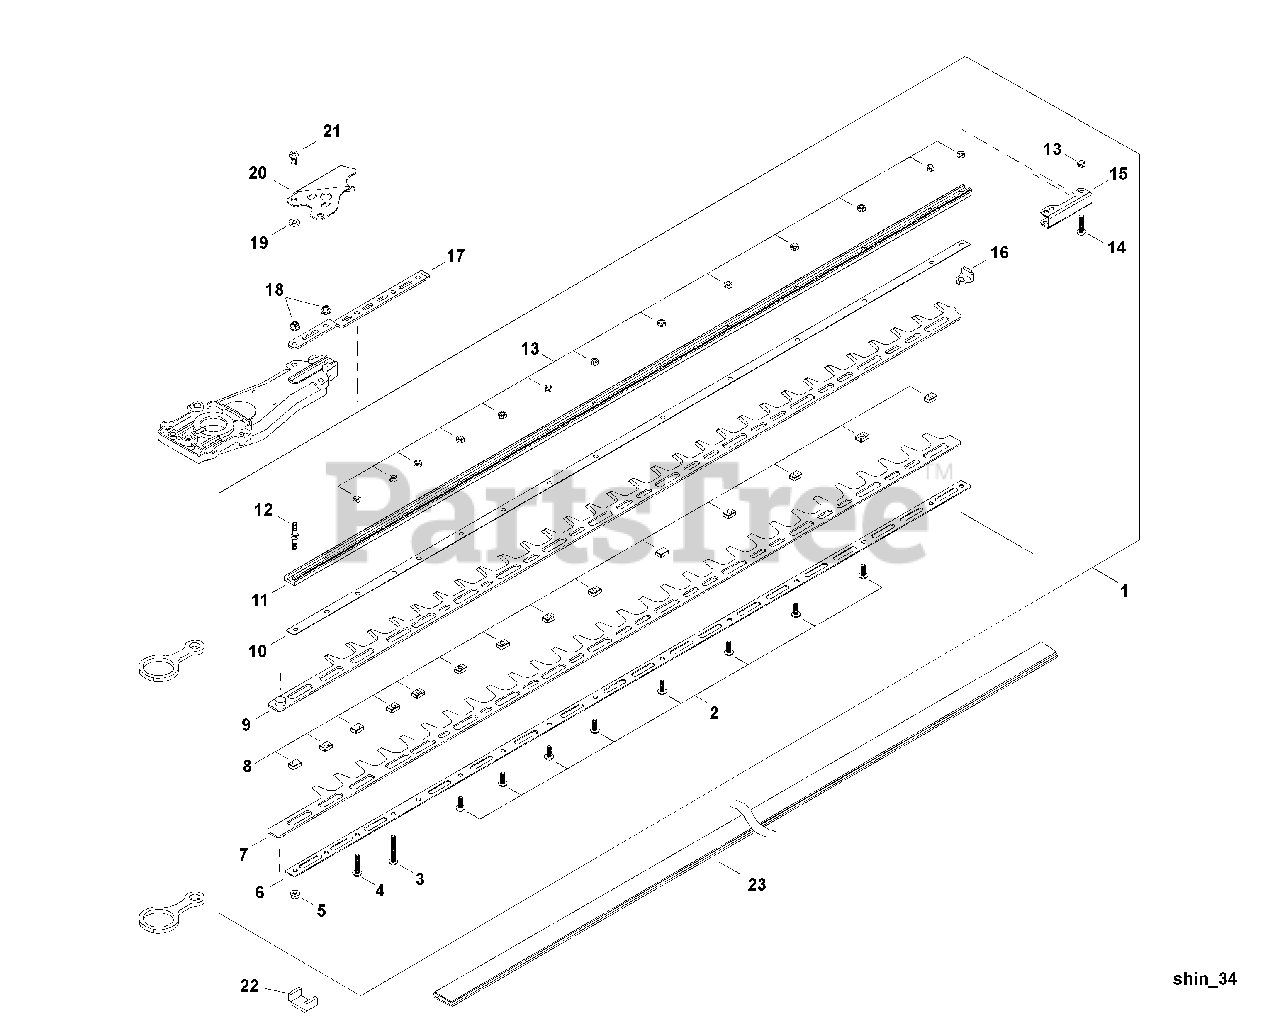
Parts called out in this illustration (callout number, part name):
1	BLADE KIT - 40" (102cm)
2	SCREW - 5X14
3	SCREW - 5
4	SCREW - 5X25
5	NUT - 5
6	PLATE - LOWER
7	BLADE - 40" (101cm) -- LOWER
9	BLADE - 40" (101cm) -- LOWER
10	PLATE - UPPER -- 40" (101cm)
11	SUPPORT, BLADE - 40" (101cm)
13	LOCKNUT - 5
14	SCREW - 5X22
15	PLATE, GUIDE
16	GUIDE, BLADE
17	PLATE, ANGLE
18	NUT - 5
19	WASHER - 5
20	PROTECTOR
21	SCREW - 6X12
22	SEAL, FELT
23	COVER, BLADE - 40" (102cm)
